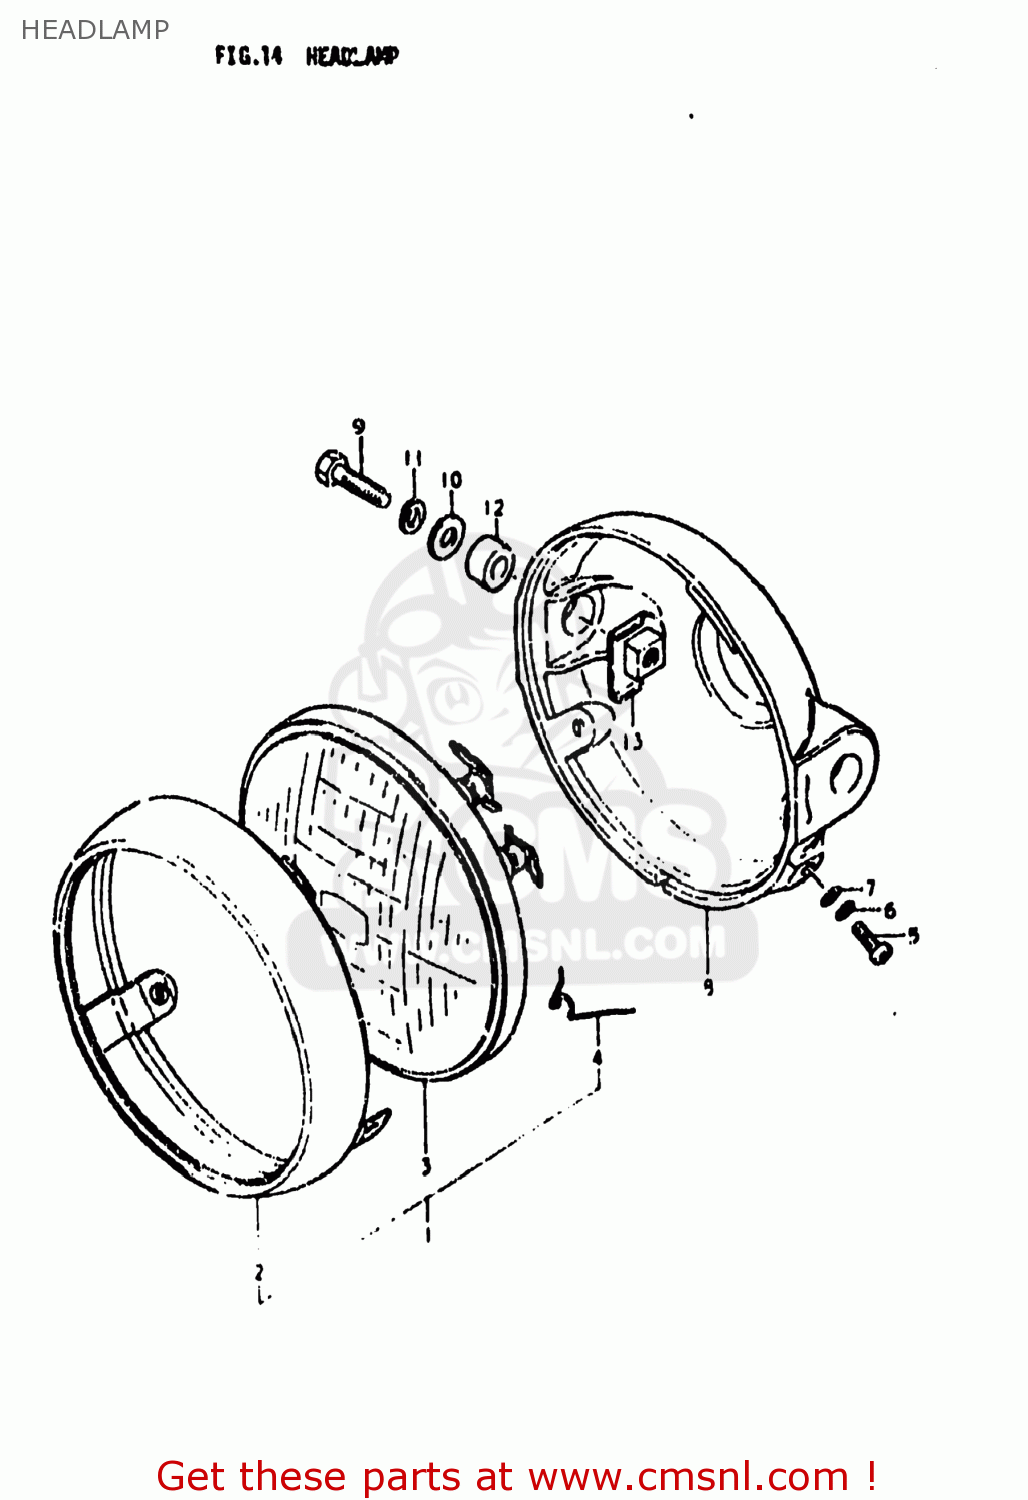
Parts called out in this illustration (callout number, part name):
1	LAMP ASSEMBLY,HEAD
2	RIM,HEADLAMP
3	GASKET,HEADLAMP LENS (NAS)
4	LENS,HEADLAMP (PLASTIC)
5	SOCKET,BULB
6	SPRING,HEADLAMP UNIT
7	BULB(6V15/15W/STANLEY,A3598HA)
8	SCREW
9	LOCK WASHER
10	WASHER
11	HOUSING,HEADLAMP
12	BOLT
13	LOCK WASHER
14	WASHER
15	SPACER (8.8X12X7)
16	PLATE,HEADLAMP HOUSING
